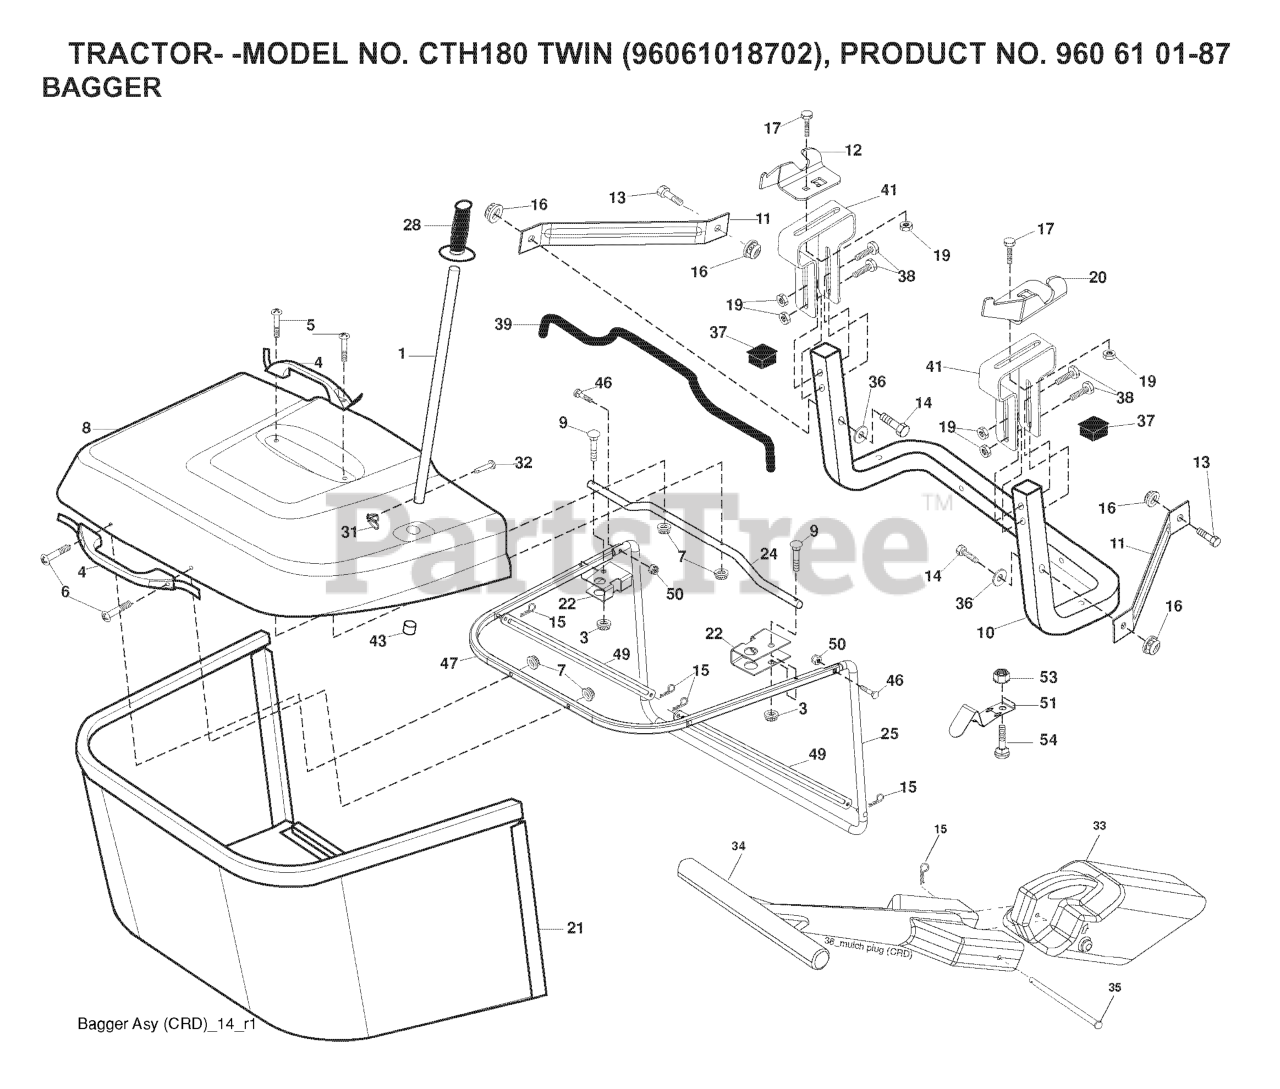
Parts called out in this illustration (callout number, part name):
1	TUBE HANDLE
3	NUT T
4	HANDLE.BAGGER.W/LVRS.BLK.CRD
5	SCREW.PAN.HEAD
6	REPL BY 532 75 00-29
8	COVER.PNT.BGR.CRD.WSLOTS.MS668
9	Bolt Carriage 1/4-20 x 2.25d x Gr.5
10	TUBE
11	BRACKET.SUPPORT.UPPER.BAG.CRD
12	BRKT PIVOT
14	BOLT-HEX EAK
15	RETAINER-SPRNG RB
16	NUT LOCK FLG 3/8-16 UNC
17	RP BOLT 5/16-18 X3/4 ZN/YEL GR
19	NUT LOCK HEX FLANGE 5/16-18
20	BRKT.PIVOT.RH.CRD
21	BAGGER.ASM.CRD.2007
22	BRKT.SIDE.BAG.CRD
24	TUBE.PIVOT.BAG.CRD.BLACK
25	PIPE
28	GRIP.HANDLE.BLACK
31	RETAINER CLIP
32	RIVET,DRILLED
33	MULCH PLUG, CTH150
34	HANDLE.MULCHER.92.CRD (2 2)
36	WASHER
37	Plug Support Bagger CRD
38	BOLT.5/16-18X2.5
39	SEAL.TRIM.37'
41	BRKT.VERT.ADJ.BAGGER.CRD
43	PLUG, TUBING END
46	BOLT.CARRIAGE.5/16-18
47	PIPE
49	ROD
50	NUT.71038.31-18.HEX.NYLOCK
51	LATCH
53	NUT
54	BOLT
